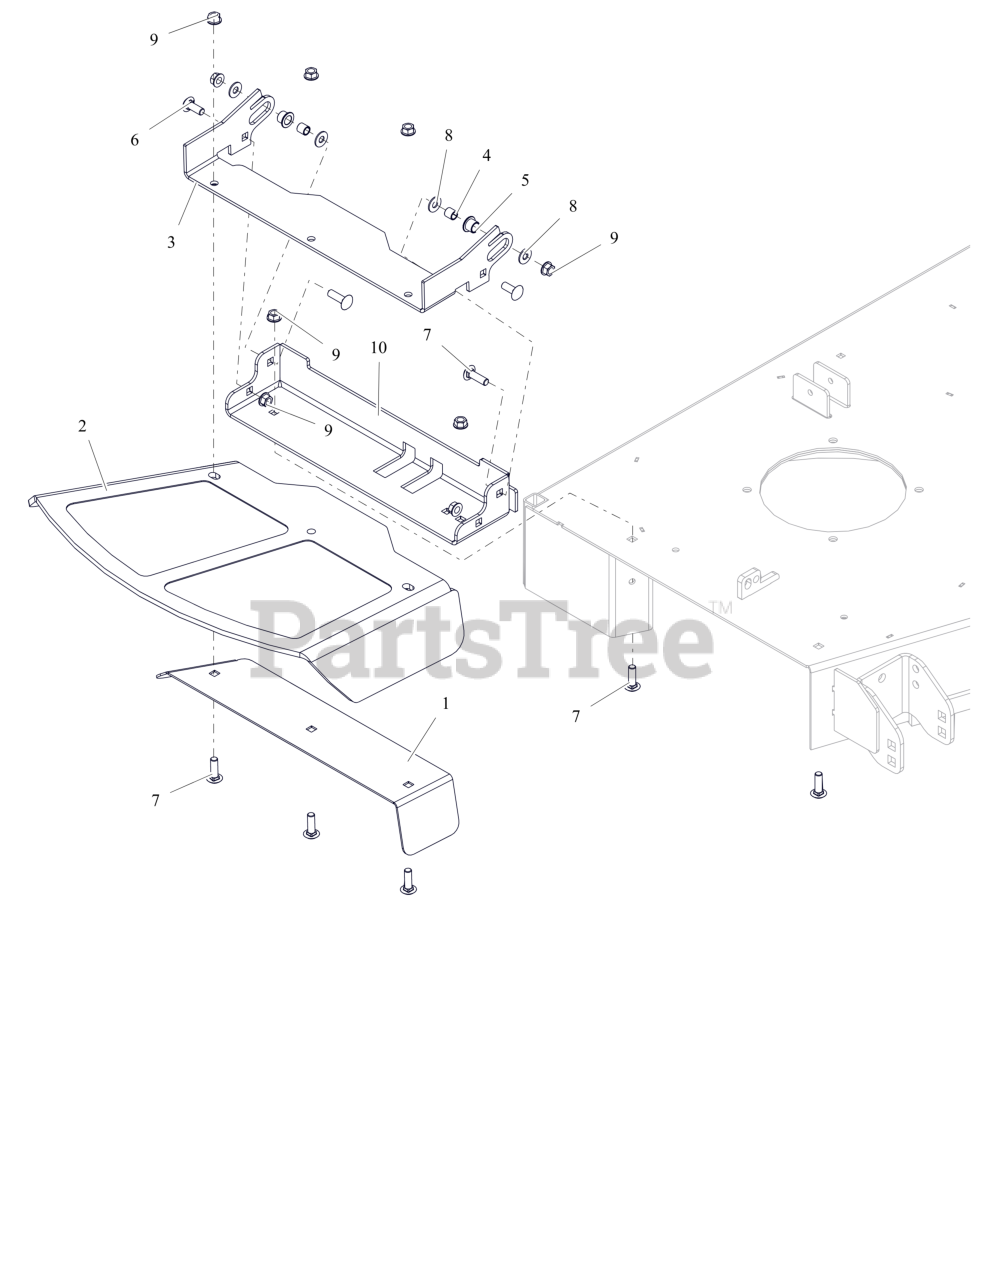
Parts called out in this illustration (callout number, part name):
1	PLT, DISCH. CHUTE CLMP-CE
2	CHUTE, FORMED RUBBER DISCHARGE
3	BRKT, CHUTE MOUNT (ORANGE)
4	SPCR, .385X.500X.350
5	BSHG, FLANGED .50X.625X.50X.062
6	BLT,RHSSN .38-16X1.00 G5 ZCC
7	BLT,RHSSN .38-16X1.25 G5 ZCC
8	WSHR, HDND .375X.875X.064 ZCC
9	NUT-LK-CTR-FLG .375-16 GF ZCC
10	BASE, DISCHARGE CHUTE MTG BRKT (ORANGE)
